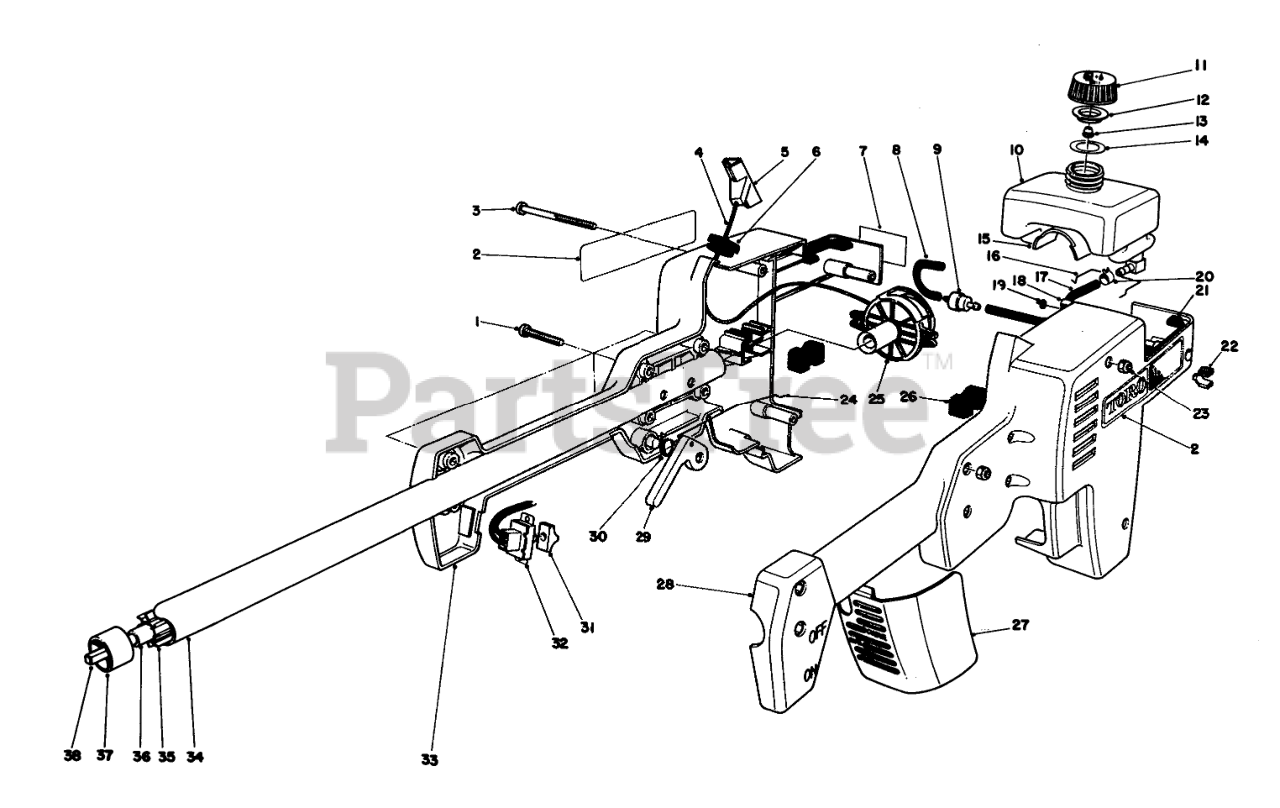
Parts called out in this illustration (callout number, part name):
1	Screw-Machine Cross Recess Pan Hd.
2	Decal-TC650
3	Screw-Machine Cross Recess Pan Hd.
4	Rope-Starter
5	Handle
6	Bushing Rope
7	Decal-Hot
8	Gas Line
9	FUEL FILTER
10	GAS TANK
11	Gas Cap Assembly (Incl . Ref. #12-14)
12	Insert-Gas Cap
13	Valve-Umbrella/Check
14	Gasket
15	Crankcase Pad
16	Clip-Crankcase Pad
17	Gas Line
18	Clamp Cable
19	Retainer-Push On
20	CLAMP-HOSE
21	Bumper-Gas Tank
22	Grommet
23	NUT-LOCK, NI
24	Link-Throttle
25	Recoil Assembly (Incl. Ref. #4-6)
26	Isolation Mount
27	Cover-Air Cleaner
28	Housing Engine L.H.
29	Lever Throttle
30	TORSION SPRING
31	SWITCH COVER-BLACK
32	SWITCH
33	Housing-Engine R.H. (Incl. Ref. #7)
34	Tube-Upper
35	Spacer-Shaft
36	Casing-Shaft
37	Retaining-Casing
38	Flexshaft
